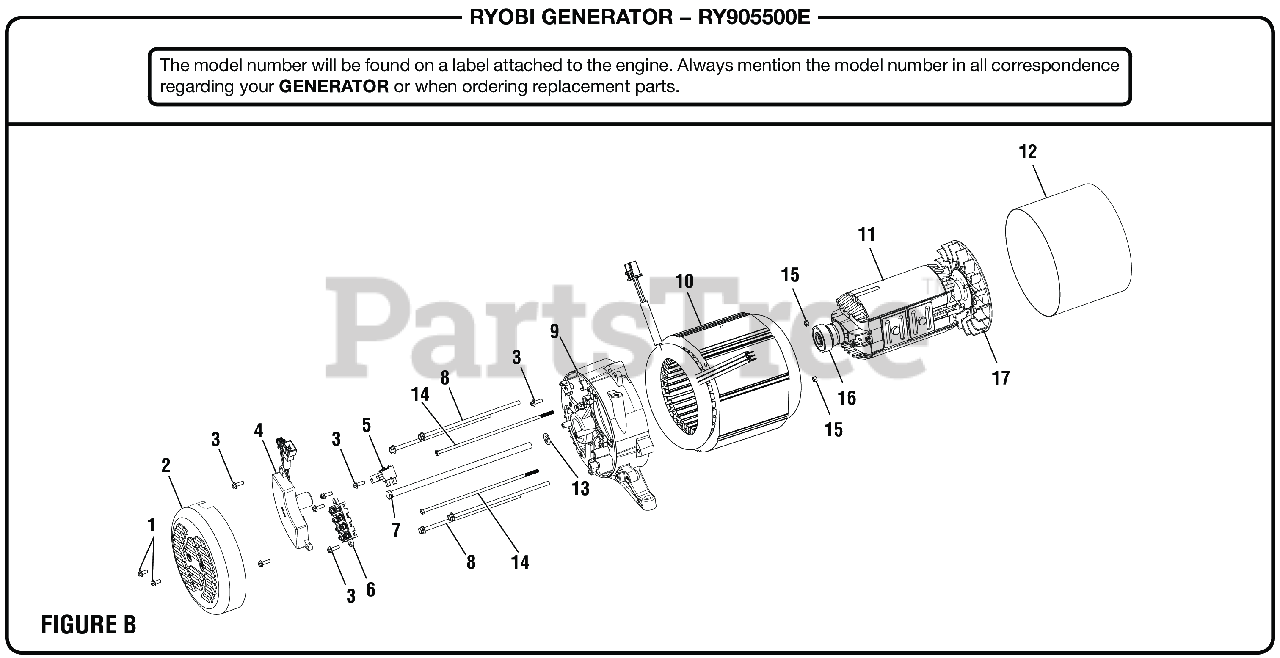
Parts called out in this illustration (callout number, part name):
1	Bolt (M5 x 12 mm, Hex Flange Hd.)
2	Brush Cover
3	Bolt (M5 x 16 mm, Hex Flange Hd.)
4	Automatic Voltage Regulator
5	Brush Assembly 190 mm
6	Terminal Block
7	Rotor Bolt (M8 x 222 mm, Flange Hex Hd.)
8	Stator Bolt (M6 x 180 mm, Flange Hex Hd.)
9	Bearing Support
12	Generator Head Cover
13	Washer (ID8.4 x OD25.1 x 3t)
14	Bolt (M5 x 200 mm, Hex Hd.)
15	Hex Nut (M5)
16	Ball Bearing
17	Fan (190 mm)
